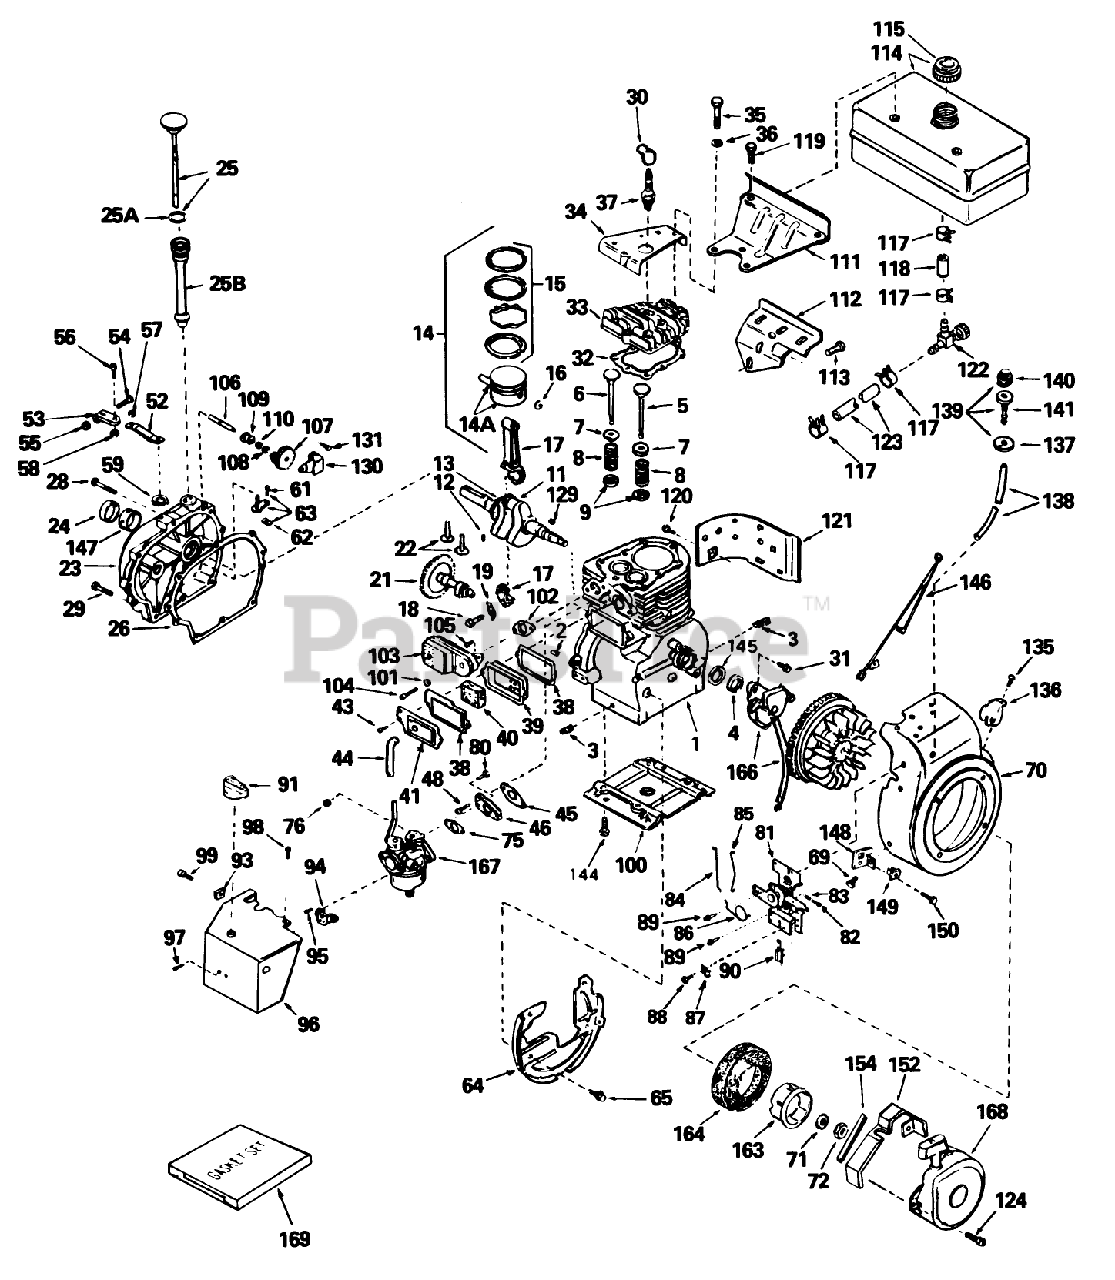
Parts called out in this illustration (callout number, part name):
1	Cylinder Assy. (Incl. Nos. 2, 3 4)
2	Pin-Dowel
3	Plug-Drain, Oil (SQH 1/4-18)
4	Oil Seal
5	Valve, Intake (Standard)(Incl. No. 9)
5	Valve, Intake (1/32" oversize)(Incl. No. 9)
6	Valve, Exhaust (Standard)(Incl. No. 9)
6	Valve, Exhaust (1/32" oversize)(Incl. No. 9)
7	Cap-Spring, Valve
8	Spring-Valve
9	Keeper-Spring, Valve
11	Crankshaft Assy. (Incl. Nos. 12 13)
12	Pin, Groove
13	Gear-Crankshaft
14	Piston, Pin Ring Assy. (Std.) (Incl. Ref. #19A, 20 21)
14	Piston, Pin Ring Assy. (.010 oversize) (Incl. Ref. #19A, 20 21 )
14	Piston, Pin Ring Assy. (.020 oversize) (Incl. Ref. #19A, 20 21)
14A	Piston Pin Assy. (Std.) (Incl. Ref. #20)
14A	Piston Pin Assy. (.010 oversize) (Incl. Ref. #20)
14A	Piston Pin Assy-. (.020 oversize) (Incl. Ref. #20)
15	ORing
15	Ring Set (.010" OS)
15	Ring Set (.020" OS)
17	Rod Assy., Connecting (Incl. Nos. 10 18)
18	Bolt, Connecting Rod
19	Dipper-Oil
21	Camshaft
22	Lifter-Valve
23	Cover, Cylinder (Incl. Nos. 24 106)
24	Oil Seal
25	Dipstick, Oil (Incl. Ref. #88)
25A	O-Ring
25B	Tube Fill
26	Gasket-Cover, Cylinder
28	Screw (1/4-20 x 1-1/4)
29	Screw
30	Cover-Spark Plug
31	Screw
32	Gasket-Cylinder Head
33	CYLINDER HEAD
34	Cover-Head, Cylinder
35	Screw (5/16-18 X 2-1/2)
36	Washer-Flat
37	Plug, Spark (J17LM or equiv.)
37	Plug, Spark (Champion RCJ-8)
38	Gasket-Breather
39	Body-Breather
40	Element-Breather
41	Cover-Valve
43	Screw
44	Tube-Breather
45	Gasket-Intake
46	Flange, Carburetor (Incl. Nos. 77 80)
48	Screw
52	Lever-Governor
53	Clamp-Lever, Governor
54	Screw
55	Nut-Lock
56	Screw
57	Washer-Lock
58	Nut-Lock
59	Ring-Retaining
61	Screw (6-40x5/16)
62	Yoke-Governor
63	Rod, Governor (Incl. Nos.62 63)
64	Baffle Blower Housing
65	Screw (1/4-20x19/32)
69	Screw, Hex Hd.
70	Housing, Blower (Incl. Ref. #135 136)
71	Washer
75	Gasket-Carburetor
76	Nut and Lock Washer (1/4-28)
80	Screw
81	Control Assy., Remote Speed (Incl. Ref. #90 thru 93)
82	Screw
83	Spring-Compression
84	Governor Link
85	Link-Throttle
86	Spring-Throttle
87	Conduit
88	Screw (10-32 x 3/8)
89	Screw (10-32 x 1/2)
90	Terminal
91	Knob-Control
93	Nut-U Type
94	Bracket-Choke
95	Screw (10-32 x 1/2)
96	Cover, Carburetor
97	Screw (8-32 X 5/16)
98	Screw (10-32x1/2)
99	Screw (8-32 x 3/8)
100	Base Engine
101	Washer
102	Gasket Exhaust
103	Muffler
104	Screw (5/16-18 X 2)
105	Screw
106	Shaft-Governor
107	Governor Gear ASM
108	Ring-Retaining
109	Spool-Governor
110	Washer-Flat
111	Bracket-Fuel Tank
112	Bracket-Fuel Tank
113	Screw (1/4-20x19/32)
114	Tank Assy., Fuel (Incl. Ref. #115)
115	Cap, Fuel
117	Clamp-Line, Fuel
118	Line-Fuel
119	Screw (1/4-15x7/8)
120	Screw
121	Emnsion, Blower Housing
122	Valve-Shut Off
123	Line-Fuel (8.62)
124	Screw
129	Key-Flywheel
130	Bracket, Governor
131	Screw (10-32 x 35/64)
135	Screw (8-32 x 3/8)
136	Screw
137	Retainer, Primer Bulb
138	Line, Primer
139	Primer Assy. (Incl. Nos. 89, 90 91)
140	Bulb, Primer
141	Body, Primer
144	Screw
145	Gasket Stator
146	Wire, Ground
147	Bushing-Crankshaft
148	Bracket
149	Grommet
150	Screw
152	Guard-Starter
154	Seal, Snowguard
163	Cup-Starter
164	Screen, Air
166	Magneto
167	Carburetor (Incl. No. 75)
168	Starter Assy., Rewind
169	Gasket Set
